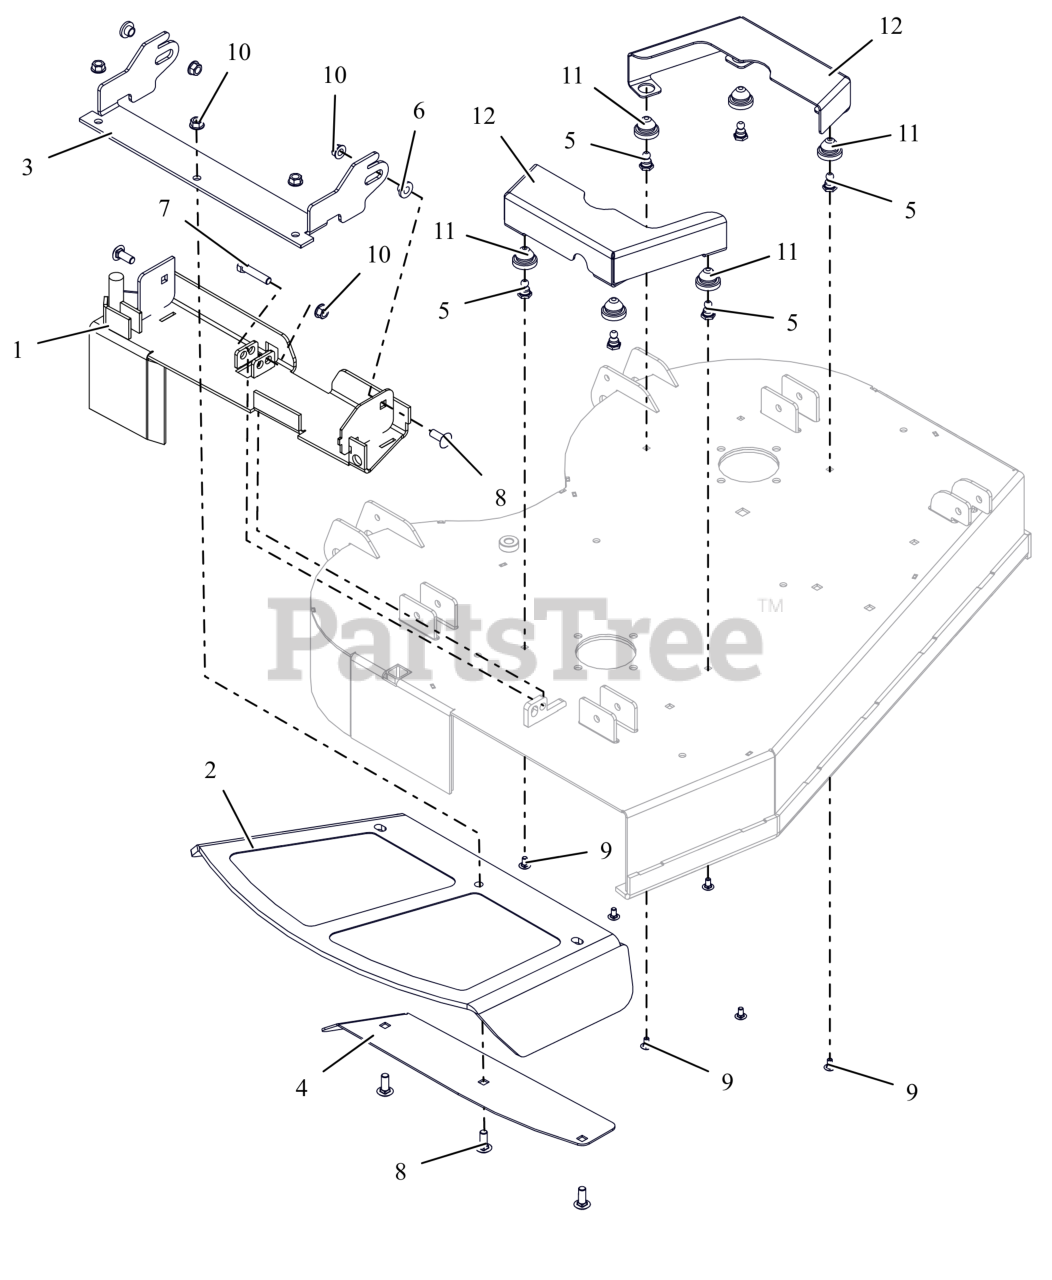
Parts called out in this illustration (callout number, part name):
1	WLDMT, DISCHARGE CHUTE (RED)
2	CHUTE,48-60" FRMD RUBBER DISCH
3	BRKT, 36" CHUTE MTG (RED)
4	PLATE, 36" DISCH CHUTE CLAMP (BLACK)
5	STUD, BALL FEMALE .250-20 THREAD
6	BSHG-FLG .385X.500X.875X.406
7	BLT, HEX .38-16X1.75F G5 ZCC
8	BLT,RHSSN .38-16X1.00 G5 ZCC
9	BLT, RHSSN.25-20X.500 G5 ZCC
10	NUT-LK-CTR-FLG .375-16 GF ZCC
11	COUPLING, RUBBER PUSH-IN
12	GUARD, 36" DECK BELT (RED)
